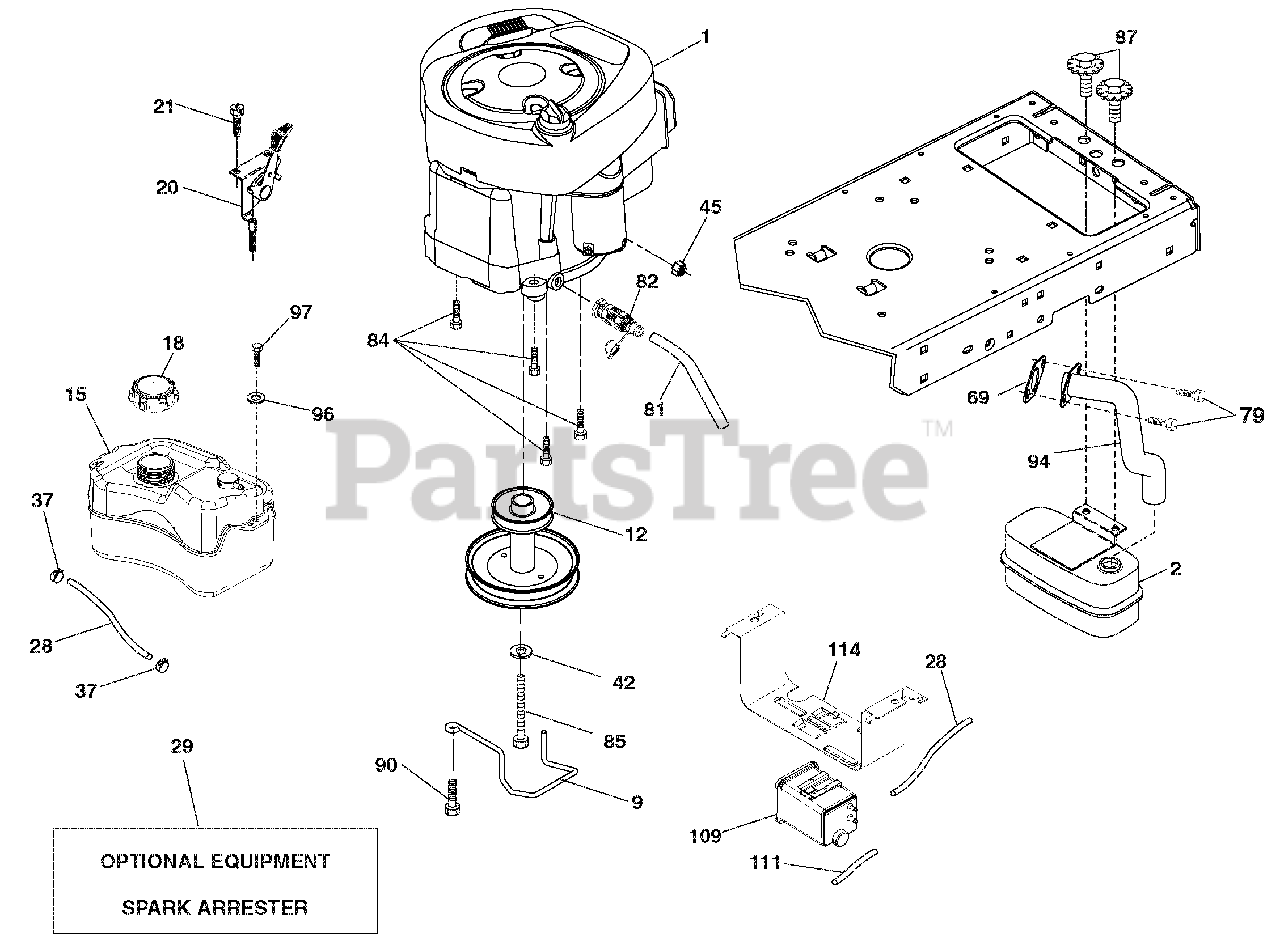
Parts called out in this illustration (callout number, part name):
1	ENGINE B&S MODEL NO. 33R877-0009-G1(586070701)(ORDER PARTS
1	FROM ENGINE MANUFACTURER.)
2	MUFFLER
9	KEEPER BELT ENGINE
12	PULLEY.ENGINE
15	TANK ASM.FUEL.1.50.CARB.CA.SVC
18	CAP FUEL
20	CONTROL THROTTLE/CHOKE
28	LINE.FUEL.22"FRONT.EMIS.CA.LP
29	KIT.SPARK ARRESTOR(392390 B&S)
37	CLAMP.HOSE.BLK.
42	WASHER.LOCK.HVY HLCL.SPR.7/16
45	Nut, Keps Hex 1/4-20 unc
69	Gasket Eng 1 313 Id Tin Plated
79	SCREW.SOCKET HD.5/16-18 X .75
81	TUBE.DRAIN.OIL.EASY
82	VALVE OIL DRAIN
84	Screw 3/8-16 x <
85	BOLT.HEX.7/16-20X4XGR5-1.5THR.
87	BOLT.5/16-18UNCX3/4 W/SEMS.BLK
90	SCREW.3/8-16X1.SMGML.TAP/R.BLK
94	EXHAUST TUBE
96	WASHER.9/32 X 7/8 X 16GA.
97	SCREW.HEXWSH.THDROL.1/4-20X3/4
109	CANISTER.CARBON.FILTER ASM.TEX
111	PURGE.LINE.CARB
114	CRADLE.CANISTER.CARBON
